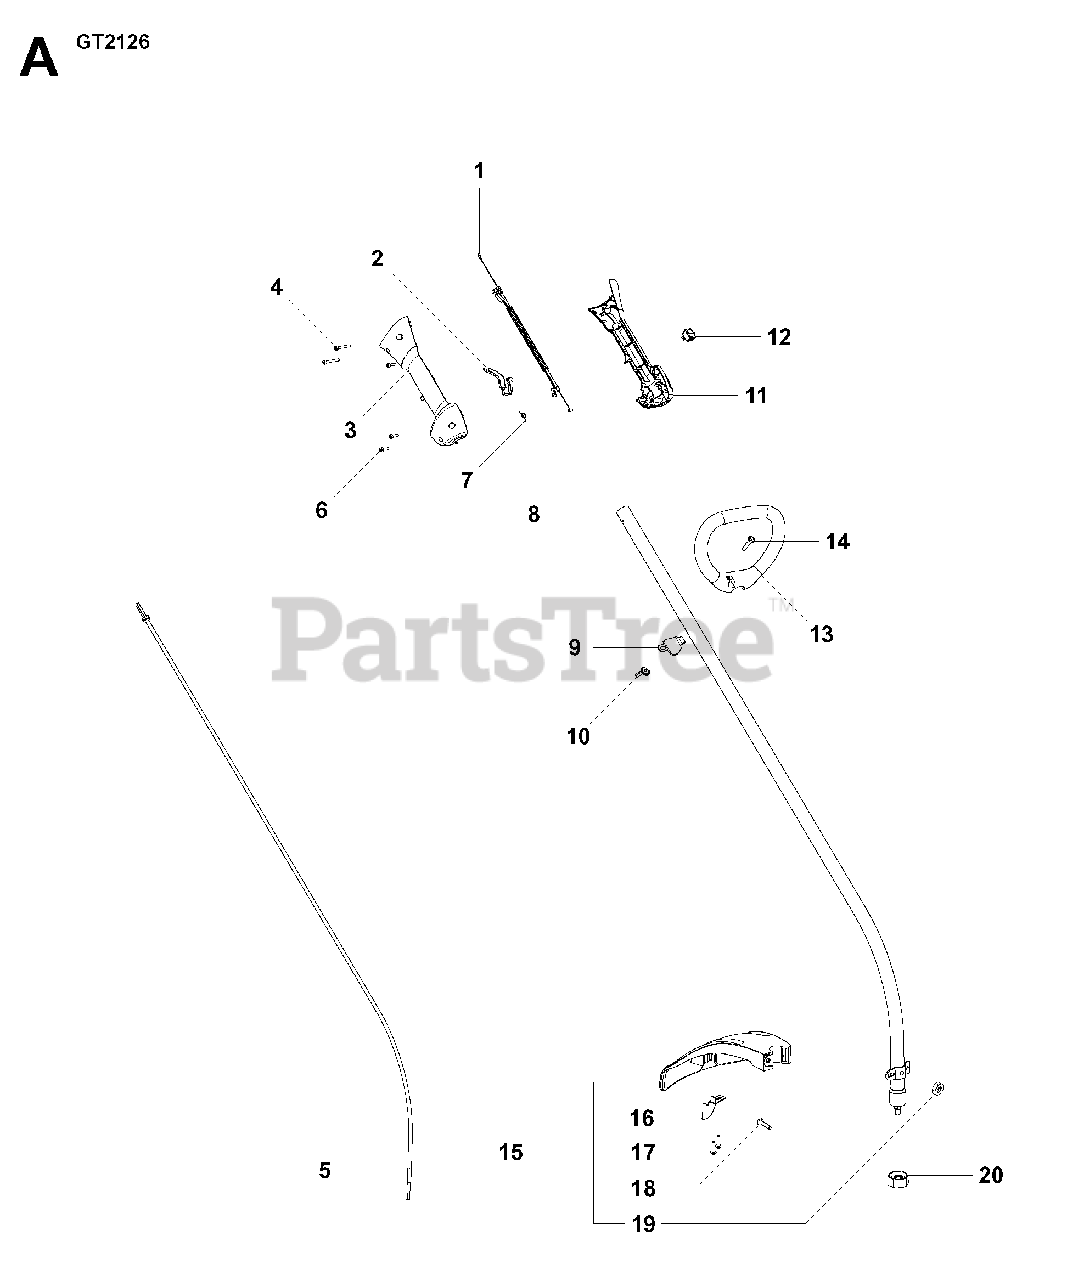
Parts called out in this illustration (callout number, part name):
1	%ASSY CABLE WIRE HARNESS
5	FLEX SHAFT "C UNIT"
6	SCREW M4 X 1.75 PT 16MM
7	SPRING TRIGGER
9	CLAMP ASSIST HANDLE
10	WINGNUT, TYPE 2
12	KIT SWITCH
13	HANDLE ASSIST
14	BOLT, TYPE 2
15	KIT SHIELD
18	BOLT, TYPE 2
